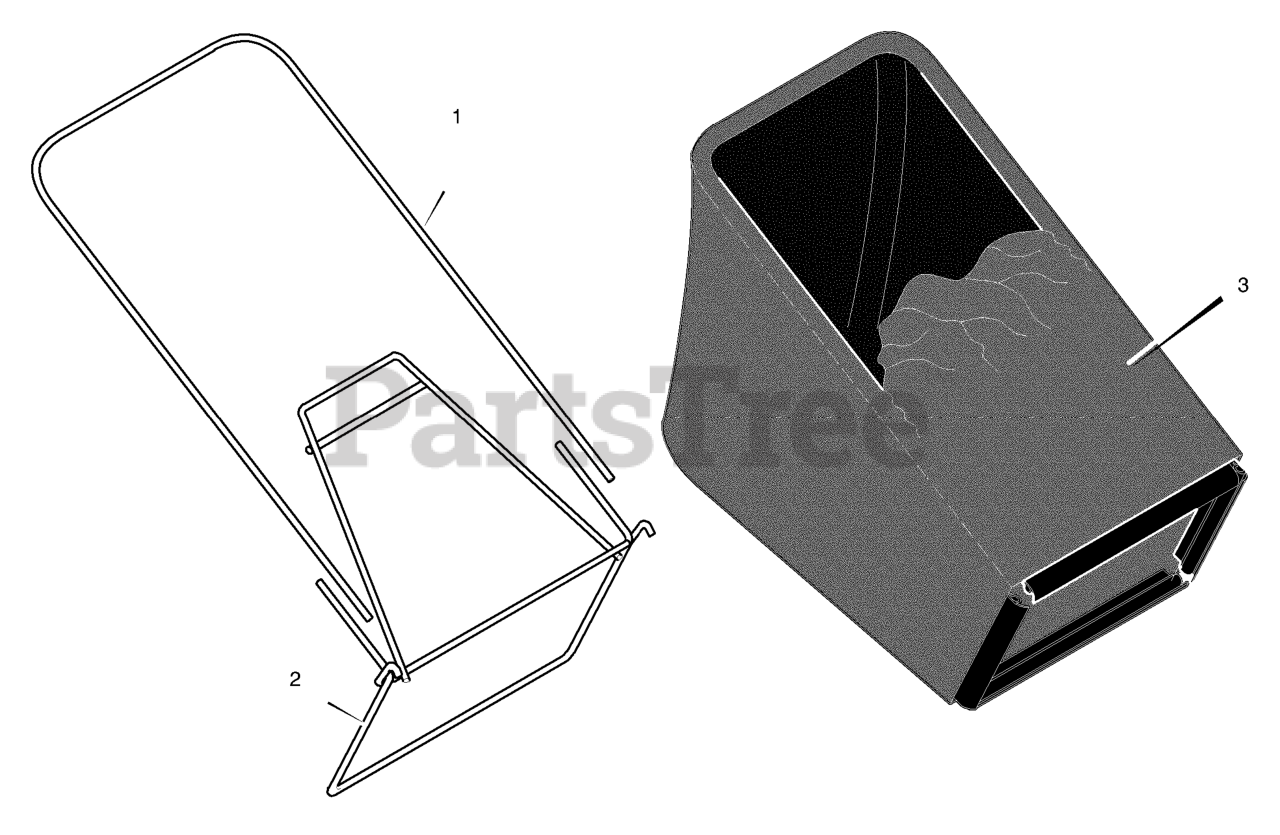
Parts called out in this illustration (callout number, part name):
1	Tube, Bag
2	Frame Assembly
3	Bag, Cloth
